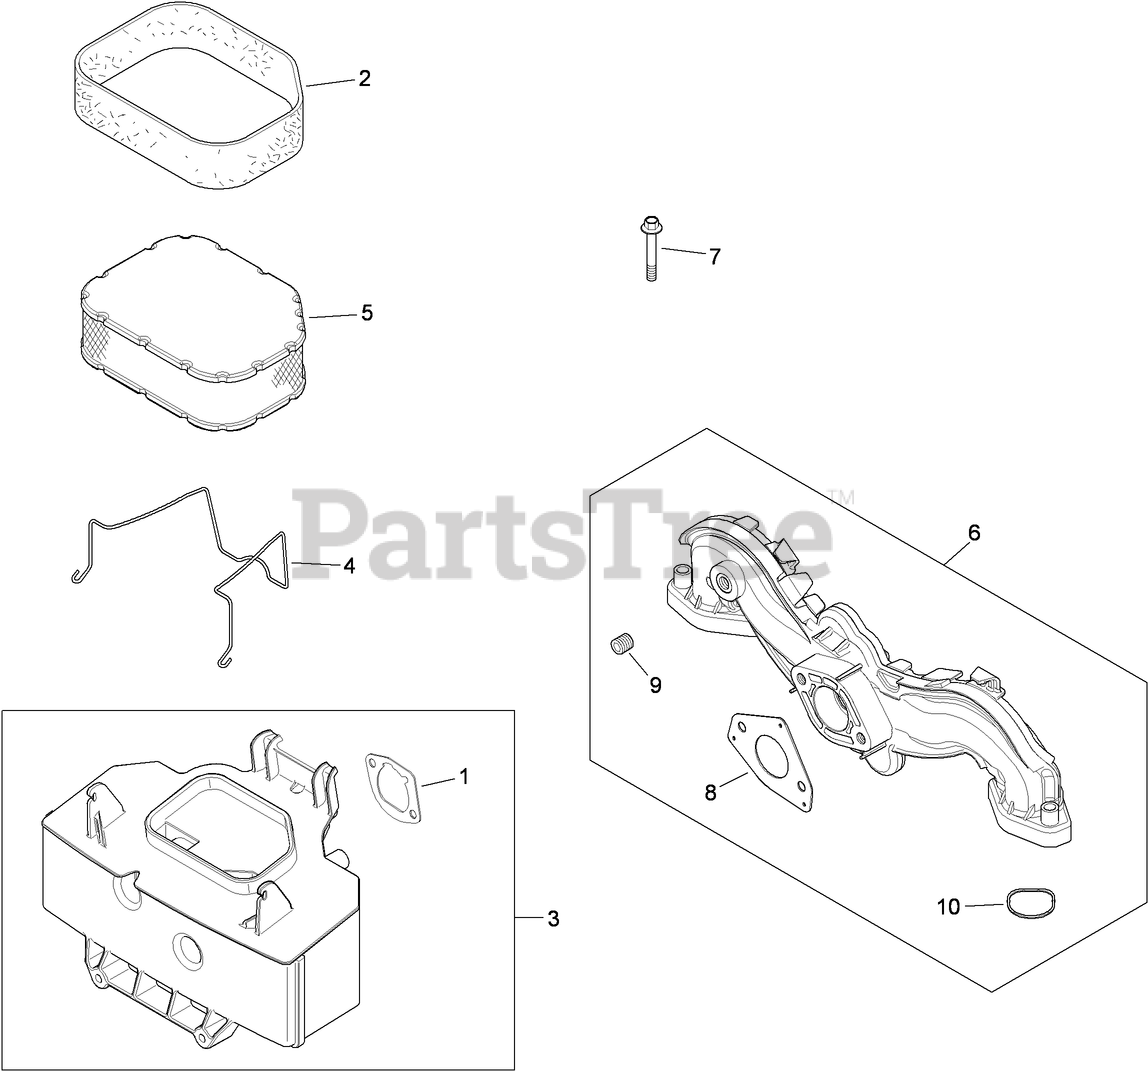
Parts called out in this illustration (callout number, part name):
1	GASKET-BASE, AIR CLEANER
2	ELEMENT-CLEANER, PRE
3	AIR CLEANER BASE KIT (INCLUDES 5-6)
4	LATCH-ELEMENT, AIR CLEANER
5	ELEMENT-FILTER, AIR
6	MANIFOLD, INTAKE (INCLUDES 2,3)
7	SCREW-FLANGE (M6X1.0X40)
8	GASKET-CARBURETOR
9	PLUG-PIPE, COUNTERSUNK (1/8)
10	O-RING
